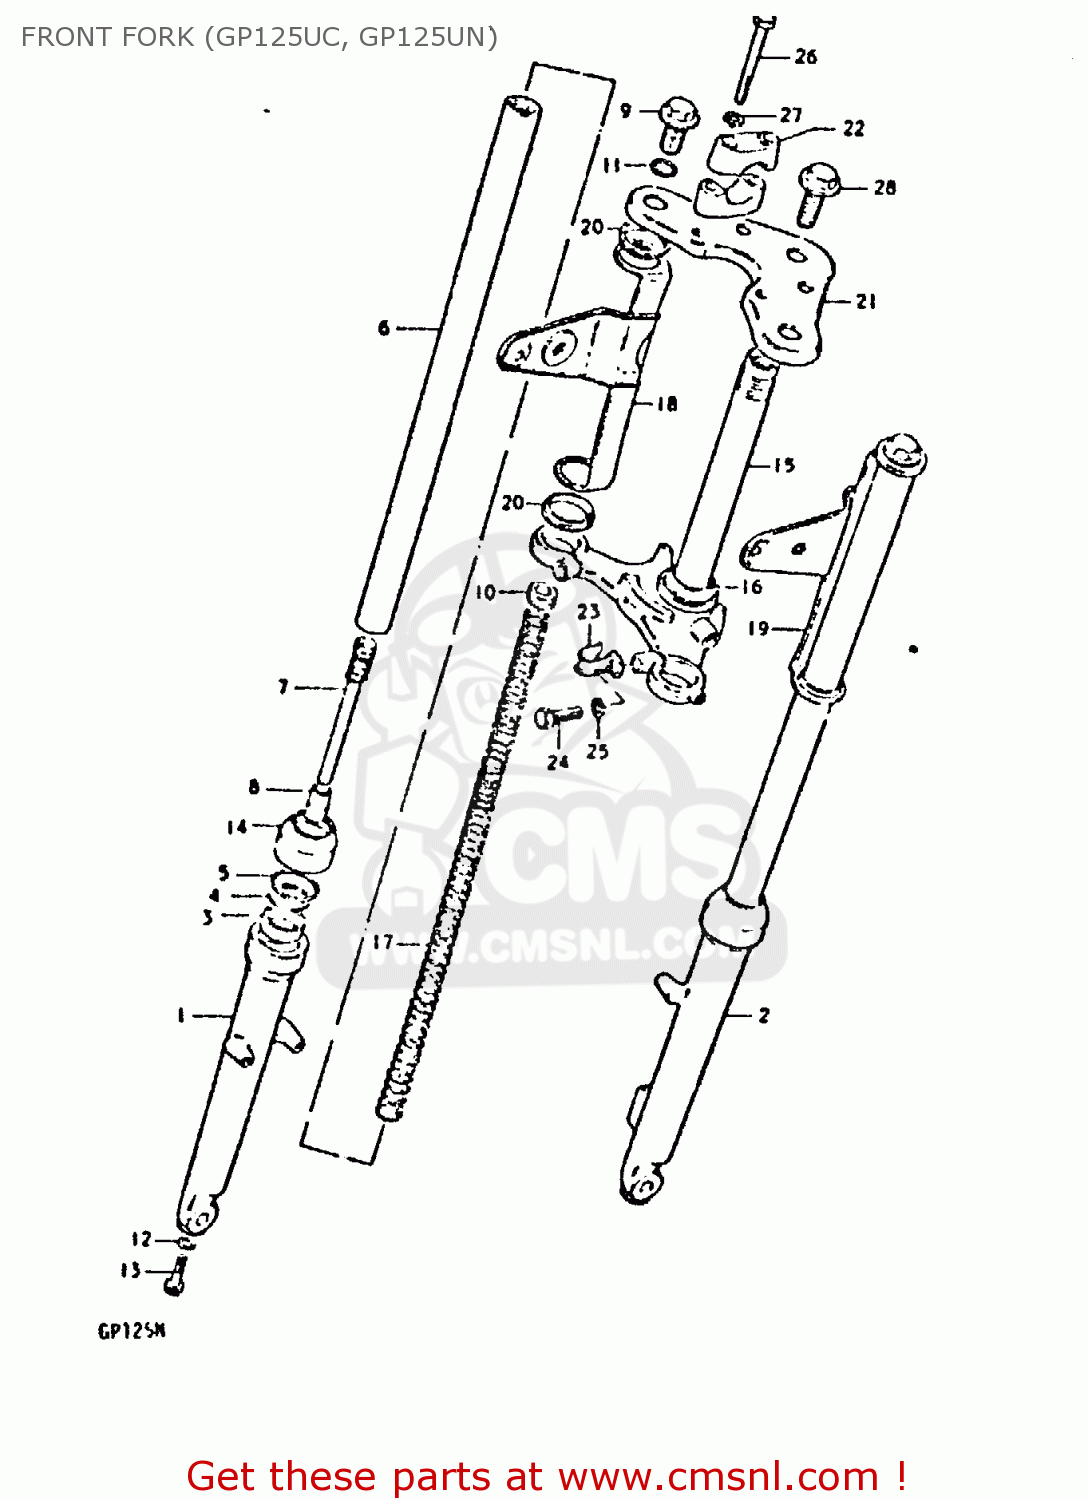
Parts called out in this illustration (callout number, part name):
1	OUTER TUBE, RH
2	OUTER TUBE, LH
3	OIL SEAL,FRONT FORK
4	WASHER,FRONT FORK
5	RING,SNAP
6	INNER TUBE
7	CYLINDER
8	PIECE,OIL LOCK
9	CAP
10	NUT
11	O RING
12	GASKET (NAS)
13	BOLT,FORK CYLINDER(10X25)
14	SEAL,DUST
15	STEM
16	RACE,STEERING OUTER LWR
17	SPRING
18	COVER, RH
19	COVER, LH
20	GASKET
21	STEM HEAD
22	HOLDER,HANDLE UPR
23	CLIP
24	BOLT,FR FORK LWR(12X33)
25	WASHER,LOCK 12
26	BOLT
27	LOCK WASHER
28	BOLT
